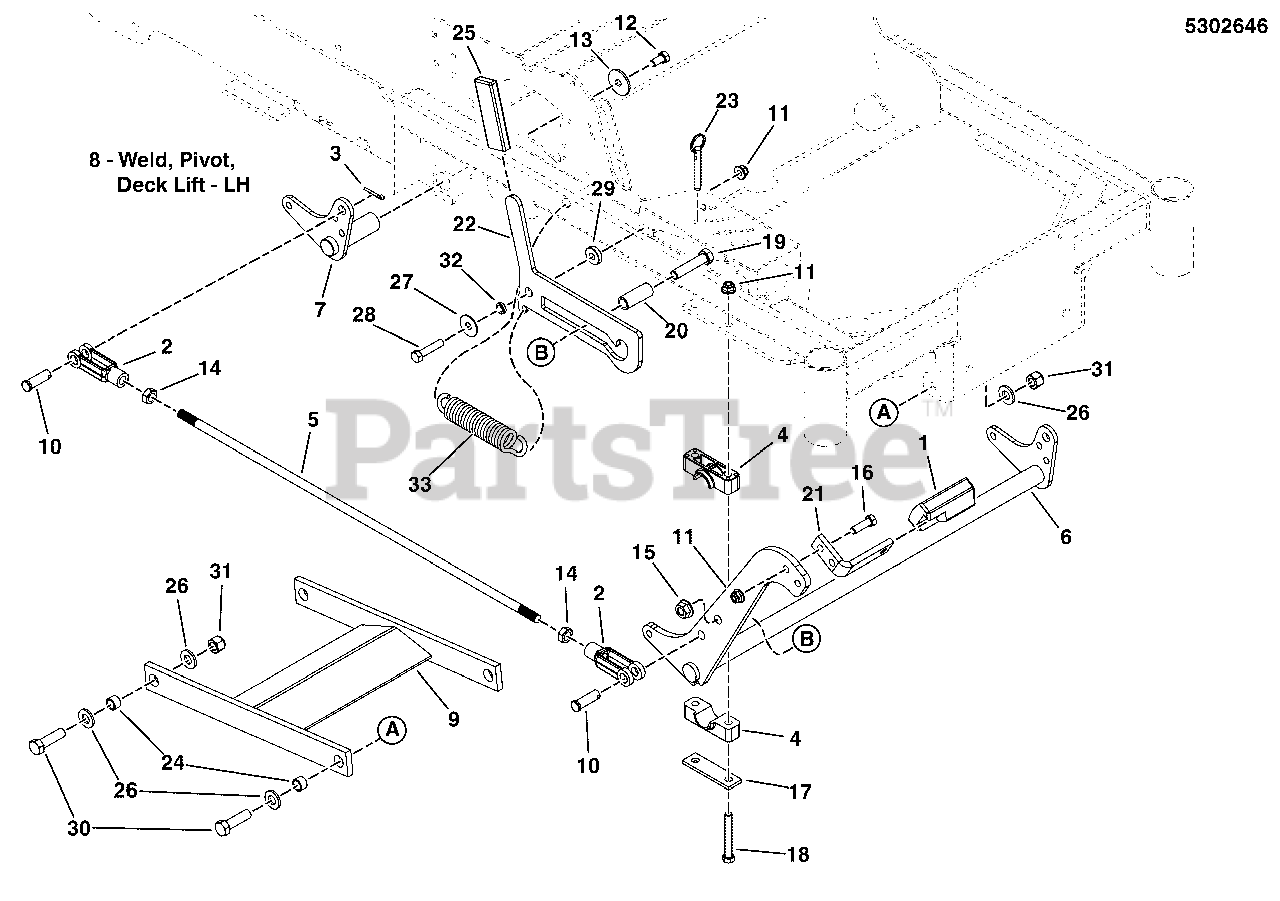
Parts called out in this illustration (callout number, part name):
1	RUBBER, FOOT PEDAL
2	CLEVIS, 1/2-20, STEEL
3	PIN, COTTER, 1/8 X 3/4
4	PIVOT BLOCK, PLASTIC
5	ROD, DECK LIFT, SNAPPER PRO
6	WELD, FRONT DECK PIVOT
7	WELD, PIVOT DECK LIFT, RH - BLK
9	WELD, PULLER BAR - BLK
10	PIN, CLEVIS, 1/2 X 1 1/2, YZP
11	NUT, 3/8-16 HEX NYLOCK FLANGE
12	BOLT, 3/8-16 X 3/4, GD5, YZ WITH PATCH
13	WASHER, .390 X 1.50 X .109, YZ
14	NUT, 1/2-20 HEX JAM
15	NUT, 1/2-13 HEX NYLOCK FLANGE
16	BOLT, 3/8-16 X 1-1/4 GD5
17	PLATE, PIVOT BLOCK SUPPORT - BLK
18	BOLT, 3/8-16 X 2-3/4 GD5 YZ
19	BOLT, 1/2-13 X 4-1/2 GD5 YZ
20	SPACER, .53 X .73 X 3.38, CZ
21	PEDAL, FOOT - BLK
22	PLATE, DECK TRANSPORT LEVER
23	HITCH PIN, 3/8 X 2-1/2, COTTERLESS, CZ
24	INSERT, BEARING
25	GRIP, FOAM, 1/4 X 1
26	WASHER, 1/2 GD9 YZ
27	WASHER-3/8 FENDER
28	BOLT, 3/8-16 X 1-3/4 GD5
29	SPACER, .39 X 1.00 X .25
30	BOLT, 1/2-20 X 1-3/4 GD8 YZ
31	NUT, 1/2-20 HEX NYLON LOCK
32	SPACER, .38 X .50 X .27, CZ
33	SPRING, EXTENSION, .50OD X 4.12 FL
